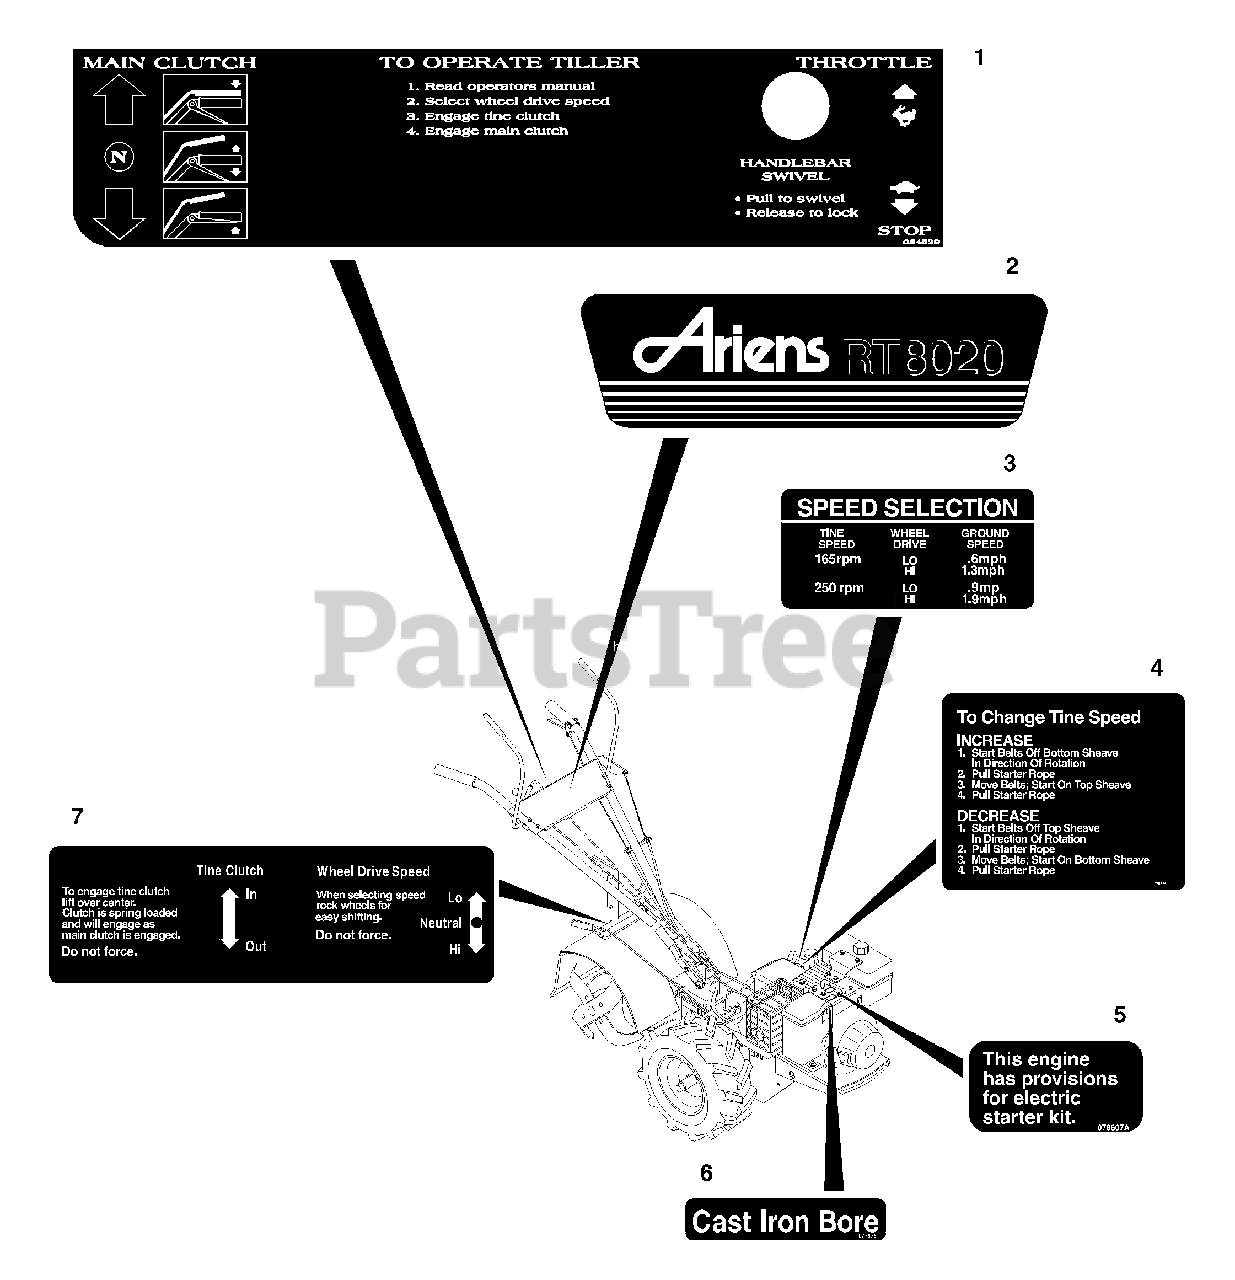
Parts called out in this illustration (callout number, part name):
1	DECAL, DASH CONTROL SER.20"
2	DECAL - RT 8020
3	DECAL - SPEED SELECT 165/250
4	DECAL -TINE SPEED CHANGE
5	DECAL, ELECTRIC START
6	DECAL - CAST IRON BORE
7	DECAL - TINE CLUTCH-DR SPEED
